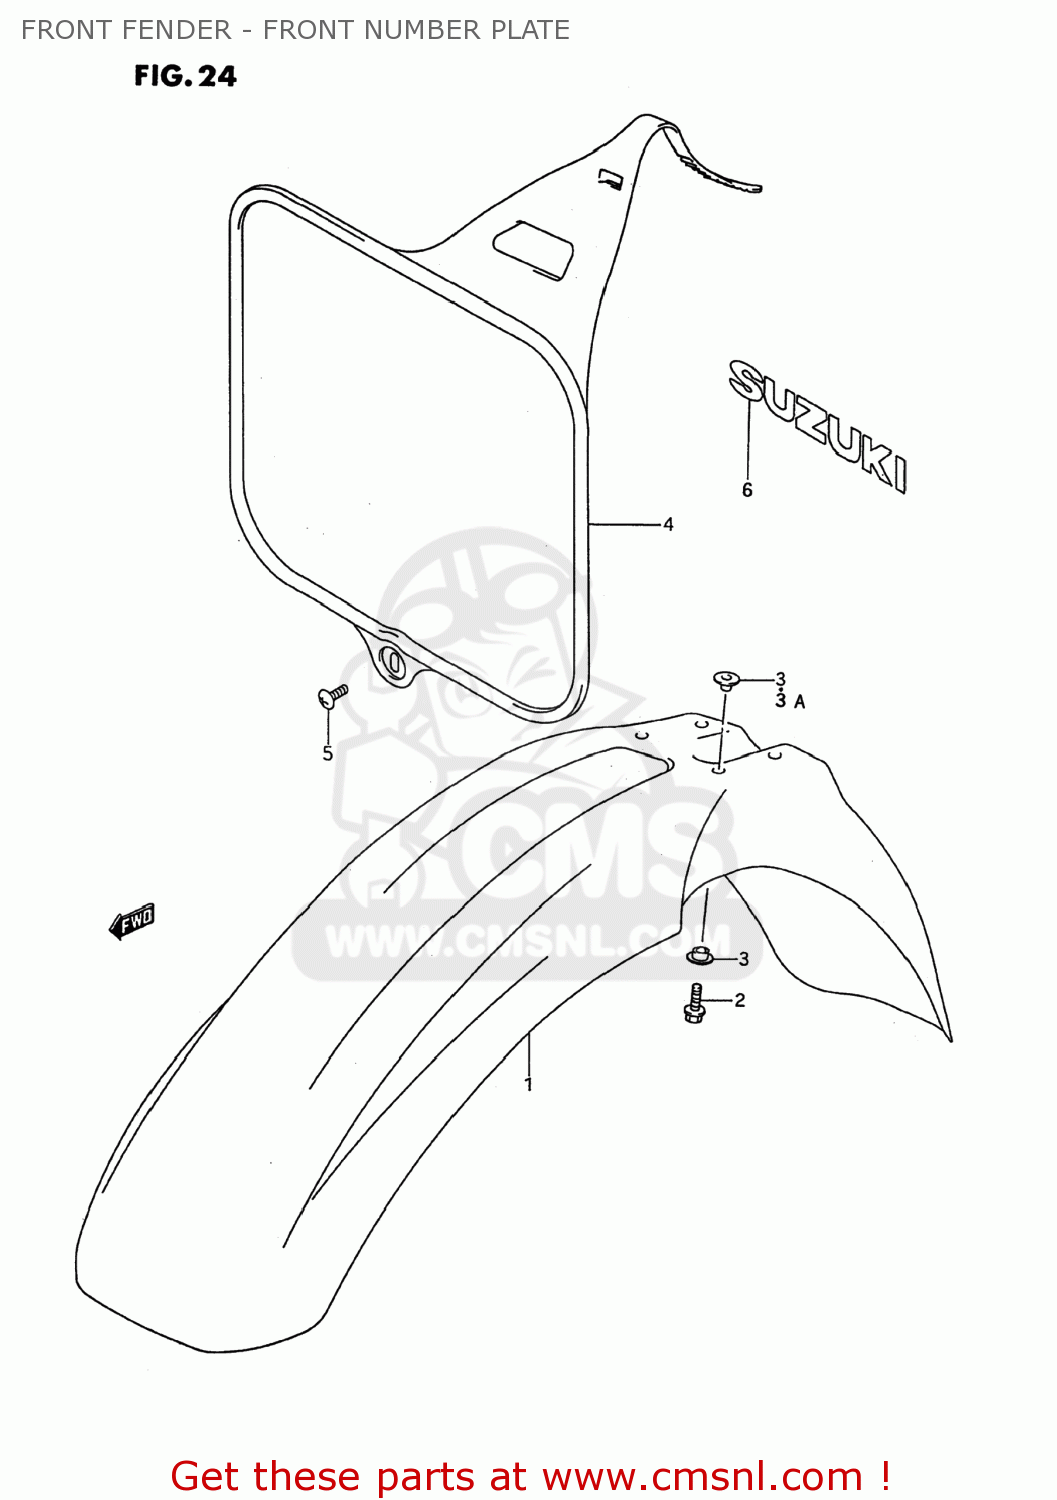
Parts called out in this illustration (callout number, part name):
1	FENDER,FRONT
2	BOLT
3	WASHER
3A	WASHER
4	PLATE,NUMBER,FRONT
5	SCREW
6	EMBLEM,FRONT NUMBER PLATE (SUZUKI)
